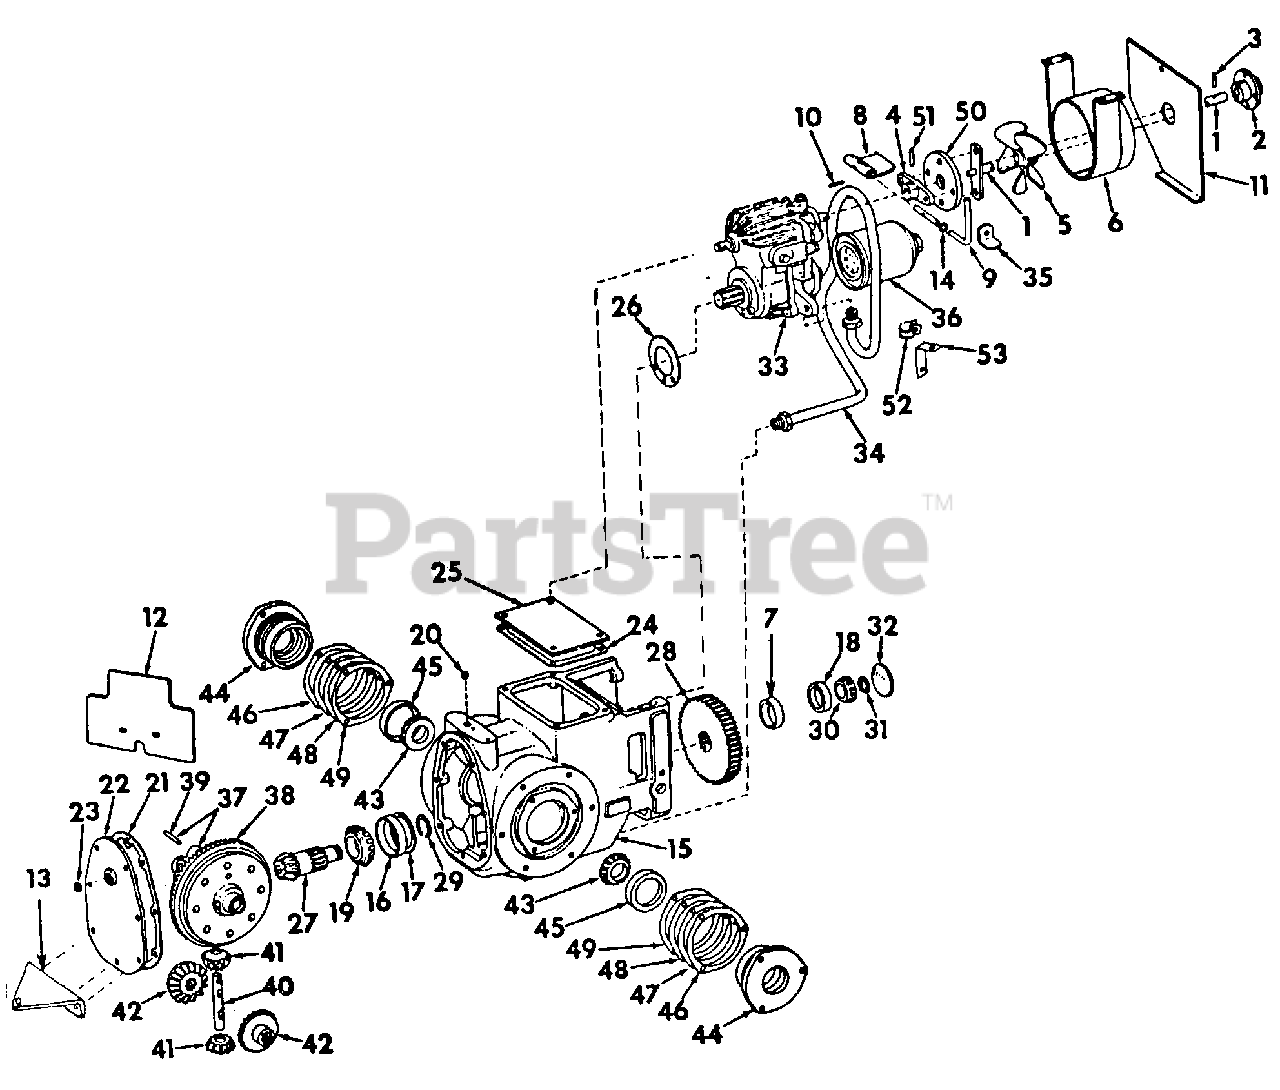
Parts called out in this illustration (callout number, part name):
1	Rod Assy, Drive
2	Hub Assy, Drive Plate
3	Pin, 1/4 X 1-1/2 Dowel
4	Arm, Coupling
6	Shroud Assy, Fan
7	Spacer, Pinion Shaft Gear
8	Actuator, Dump Valve
9	Rod, Dump Valve
10	Pin, 1/8 X 3/4 C-Z Hv Coiled Spring
11	Plate, Air Baffle
12	Shield, Rear Cover
13	Drawbar, Fixed
14	Grommet, Rubber
15	Case Assy, Transmission
16	Bearing, Bevel Pinion Shaft Rear Cup
17	Shim, Rear Brg Cup, .004
18	Bearing, Bevel Pinion Shaft Front Cup
19	Bearing Assy, Bevel Pinion Shaft Rear Cone
20	Plug, Breather
21	Gasket, Rear Cover Plate
22	Plate Assy, Rear Cover
23	Plug, 1/2-14 Automotive Sq-Soc-Hd Drain
24	Gasket, Top Cover
26	Gasket, Front
27	Shaft, Bevel Pinion
28	Gear, Constant Mesh -66T
29	Ring, Gear Retainer
30	Bearing Assy, Bevel Pinion Shaft Front Cone
31	Ring, Pinion Shaft Front Brg Retainer, .125
32	Plug, 2-1/8 Expansion
33	Transmission Assy, Hydrostatic Drive
34	Tube Assy, Suction
35	Bracket, Lever Retaining
36	Filter Assy
37	Case, Differential w/Drive Gear
38	Gear, Drive -46T
39	Pin, Pinion Shaft Lock
40	Shaft, Pinion
41	Pinion -10T
42	Gear, Side
43	Bearing Assy, Cone
44	Cage Assy, Differential Brg
45	Bearing, Cup
46	Shim, Bearing Retainer, .004
47	Shim, Bearing Retainer, .007
48	Shim, Bearing Retainer, .0149
49	Shim, Bearing Retainer, .0299
50	Disc, Flexible Coupling
51	Pin, 1/4 X 1-3/4 Hv Coiled Spring
52	Clip, Suction Tube
53	Bracket, Suction Tube
